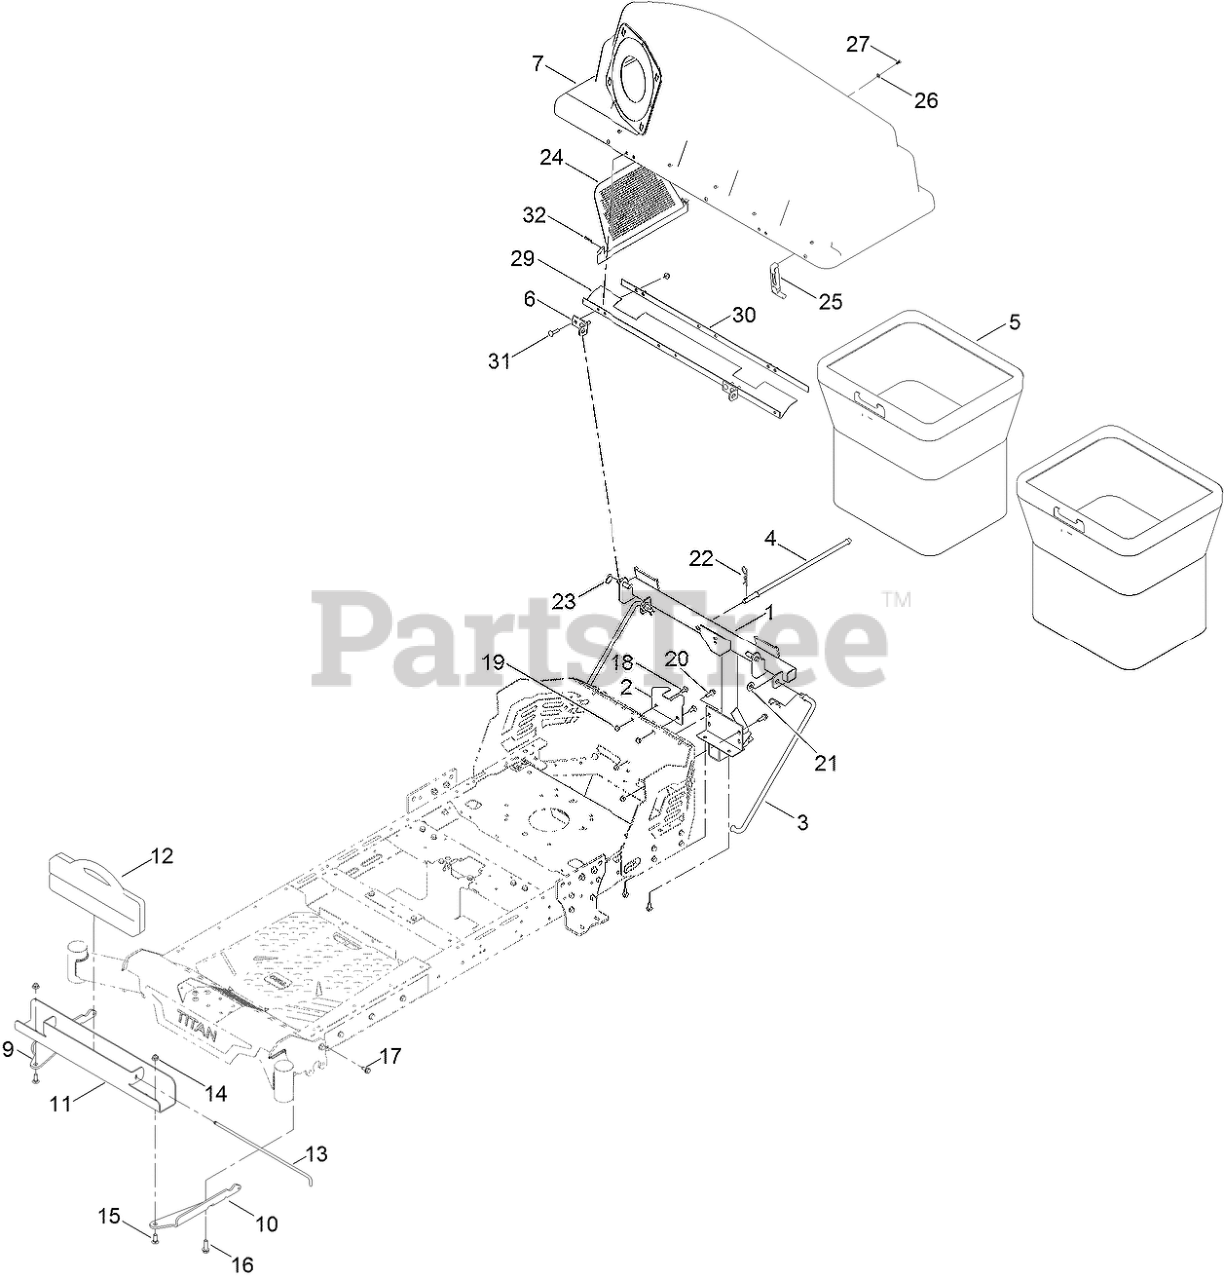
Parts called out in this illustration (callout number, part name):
1	FRAME-PIVOT
2	SUPPORT-UPPER
3	ROD-SUPPORT
4	ROD-HOOD, DOWN (HOLD)
5	BAG ASM
6	BRACKET-HOPPER PIVOT
7	BAGGER HOOD ASM
9	BRACKET-WEIGHT, RH
10	BRACKET-WEIGHT, LH
11	CHANNEL-WEIGHT, BAGGER
12	WEIGHT-35 POUND
13	ROD, WEIGHT LOCK
14	NUT-HF, NI
15	BOLT-CARR
16	SCREW-HHF
17	SCREW-HWHTF
18	BOLT-CARR
19	NUT-HF
20	SCREW-HHF
21	WASHER-FLAT
22	PIN-HAIR
23	PIN-COTTER, CIRCULAR
24	SCREEN-BAGGER
25	LATCH-RUBBER
26	WASHER-PLAIN
27	SCREW-PPH
30	PLATE-BACKING
31	BOLT-CARRIAGE
32	PIN-HAIR
